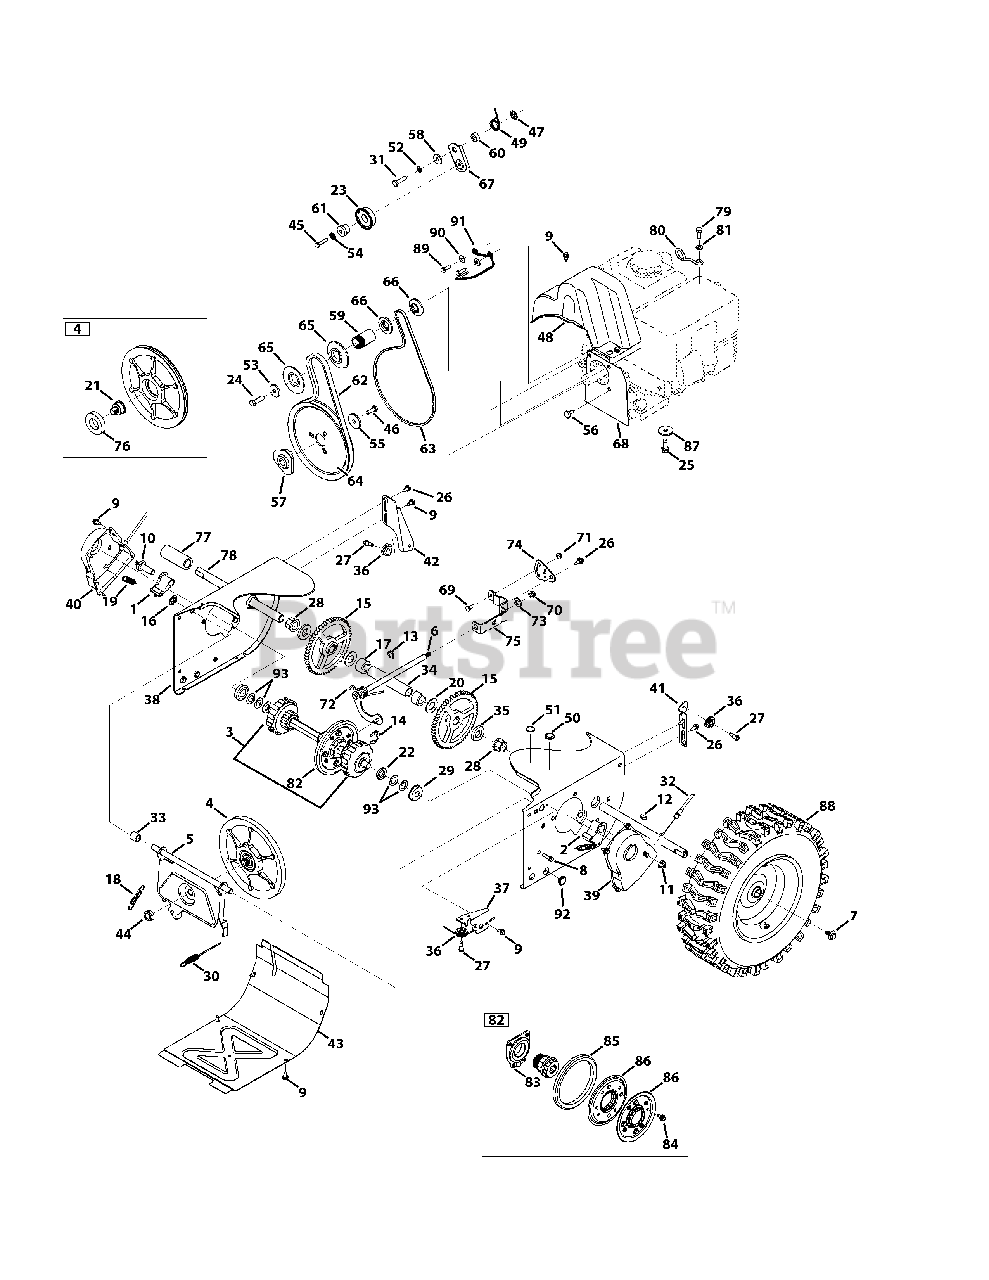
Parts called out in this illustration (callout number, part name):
1	Dogg Assembly, RH
2	Dogg Assembly, LH
3	Drive Shaft Assembly
4	Friction Wheel Disc Assembly
5	Friction Wheel Support
6	Rod Shift Assembly
7	Screw, 5/16-24 x .750
8	Screw, 1/4-20 x 1.000
9	Screw, 1/4-20 x .625
10	Actuator Shaft
11	Nut, Flangelock, 3/8-16
12	Hi-Pro Key, 3/16 x 3/4 DIA
14	Retainer Ring
16	Nut, Speed, .500
17	Spacer, .76 x .75
18	Extension Spring, .380 x 2.500
19	Extension Spring, .500 x 1.71
20	Washer, Flat, .76 x 1.49
21	Friction Pin, Disc Bearing
22	Spacer, .68 ID x 1.25 OD x .20
23	Pulley Assembly
24	Hex Head Screw, 3/8-24 x 1.25
25	Taptite Sems Screw, 3/8-16 x 1.000
26	Screw, Shoulder, .368 x .113 x 1/4-20
27	C Screw, Shoulder, .340 x .335 x 1/4-28
28	Hex Flange Bearing, .75 ID
29	Ball Bearing, 17 x 40 x 12
30	Drive Clutch Cable
31	Hex Head Screw, 5/16-24 x 1.25
32	Steering Cable
33	Spacer, .508 x .75
34	Axle Support Tube
35	Spacer, Axle
36	Roller Cable
37	Auger Cable Guide Bracket
38	Wheel Drive Frame
39	Shaft Retainer, LH
40	Shaft Retainer, RH
41	Auger Clutch Cable Guide Bracket
42	Drive Clutch Cable Guide Bracket
44	Nut, Flange, 5/8-18
45	Taptite Screw, 1/4-20 x 1.250
46	Hex Head Screw, 5/16-24 x .875
47	Nut, Push-On, .25 DIA
48	Belt Cover
49	Spring, Torsion, .850 x .333
50	Plug, 3/8 ID
51	Plug, 1/2 ID
52	Washer, Lock, 5/16
53	Washer, Flat, .45 x 1.5
54	Washer, Lock, 1/4
55	Washer, Flat, .34 x 1.50
56	Screw, Shoulder
57	Pulley Adapter, .75 DIA
58	Spacer, Shoulder, .3175 x .500
59	Spacer, .875 x 1.185
60	Spacer, .340 x .750
61	Spacer, Shoulder, .260 x .785
62	Belt, .500 x 37.00
63	V Belt, 3/8 x 35.68"
64	Auger Pulley, 8.1 x .5
65	Pulley, Half, 4L-V x 2.600
66	Pulley, Half, 3/8-V x 1.7160
67	Drive Idler Bracket
68	Cover Plate
69	Hex Head Screw, 1/4-20 x .620
70	Nut, Flangelock, 5/16-18
71	Nut, Flangelock, 1/4-20
72	Spring, Torsion, .750 x .968
73	Washer, Flat, .469 x .875 x .105
74	Speed Selector Pivot Bracket
75	Speed Selector Shift Bracket
76	Ball Bearing, 30 x 55 x 13
77	Spacer, 1.25 x .75 x 3.00
78	Axle, .75 x 11.12
79	Hex Head Screw, 1.25 x 20
80	Cable Guide
81	Washer, Flat, .330 x .630
82	Friction Wheel Assembly
83	Bearing Assembly, Friction Wheel
84	Screw, 5/16-18 x .750
85	Friction Wheel, 5.5 OD
86	Friction Wheel Plate
87	Washer, Flat, .38 x 1.38
88	Wheel, LH, 16 x 6.5-8
88	Wheel, RH, 16 x 6.5-8
89	Hex Head Screw, 5/16-24 x 1.00
90	Washer, Flat, .349 x .879
92	Plug, 5/8 Hole
93	Flat Washer, .67 x 1.174 x .02
